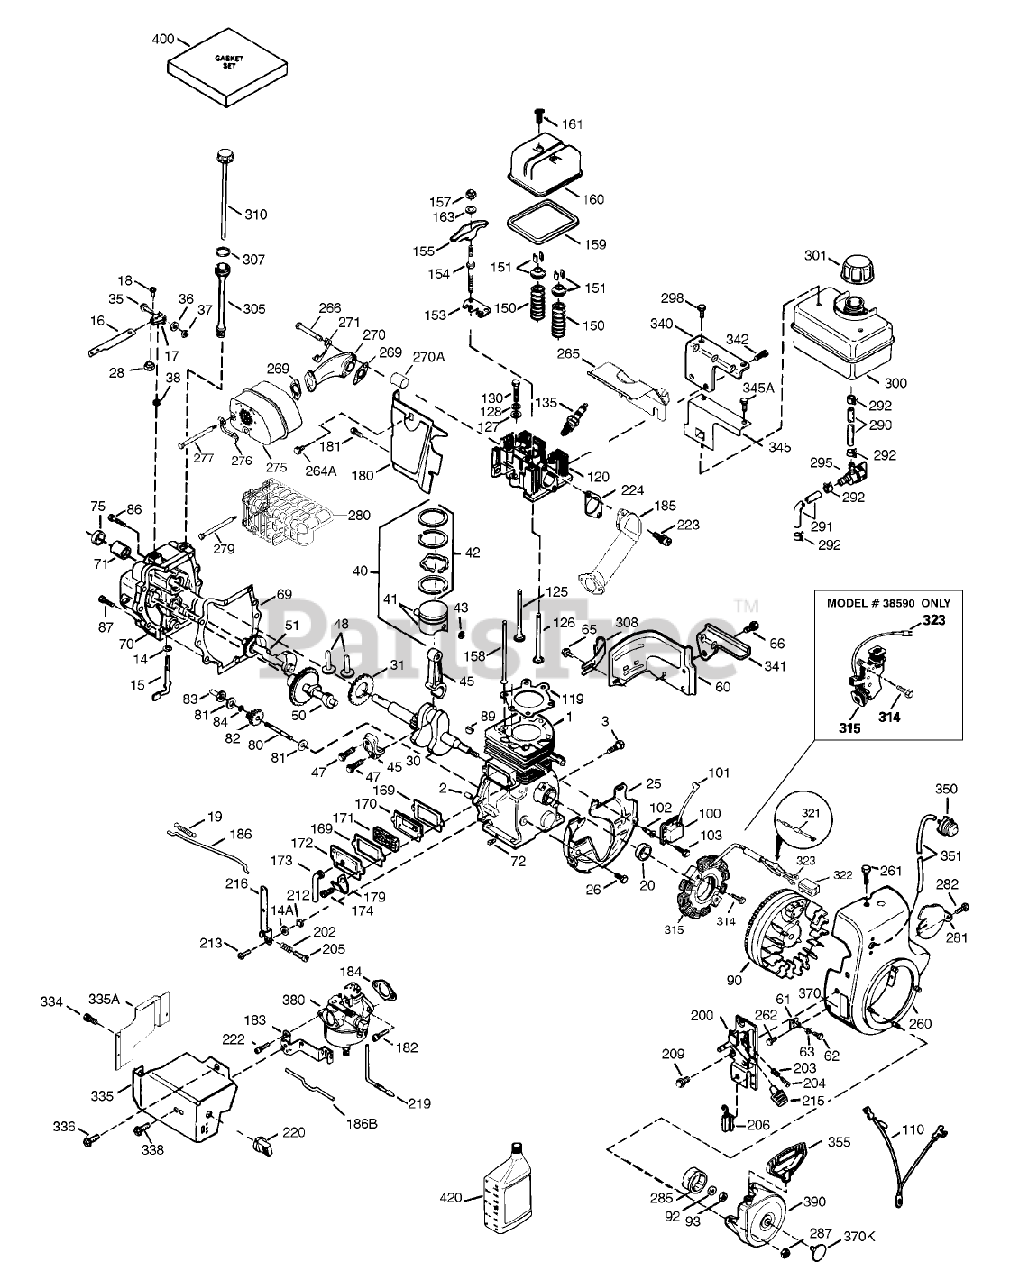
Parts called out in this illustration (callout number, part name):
1	Cylinder (Incl. 2, 20, 72 80)
2	Pin-Dowel
3	Screw (1/4-20x1/2)
14	Washer-Flat
14A	Washer
15	Governor Rod (Incl. Ref.#14 38)
16	Governor Lever
17	Clamp-Lever, Governor
18	Screw (T-15, 8-32x7/16)
19	Throttle Spring
20	Seal-Oil
25	Baffle-Housing, Blower
26	Screw (1/4-20x19/32)
28	Nut-Lock
30	Crankshaft
31	Counterbalance Gear
35	Screw
36	Washer-Lock
37	Nut-Lock
38	Ring-Retaining
40	Piston Pin and Ring ASM (STD)
40	Piston Pin and Ring ASM (.010)
40	Piston Pin and Ring ASM (.020)
41	Piston Pin Ass-y(Std.)(Incl. 43)
41	Piston Pin Ass-y (.010" OS)(Incl. 43)
41	Piston Pin Ass-y.(.020" OS)(Incl. 43)
42	Ring Set (STD)
42	Ring Set (.010)
42	Ring Set (.020)
43	Retaining Ring-Piston Pin
45	Connecting Rod ASM (Incl. Ref. #47)
47	Bolt-Rod, Connecting
48	Lifter-Valve
50	Camshaft
51	Counterbalance Weight
60	Extension-Housing, Blower
61	Bracket
62	Screw (8-32 x 3/8)
63	Grommet
65	Screw (10-24 x 9/16)
66	Screw (1/4-20x19/32)
69	55072/75/86/89 TWO
70	Cylinder Cover (Incl. Ref. #14, 15, 38, 71, 75)
71	2025A77 WIZARD ROTA
72	Plug-Drain, Oil (SQH 1/4-18)
75	Seal-Oil
80	Governor Shaft
81	Washer
82	Gear-Asm Governor
83	Governor Spool
84	Ring-Retaining
86	Screw (1/4-20x1-3/16)
87	Screw (1/4-20x1-11/16)
89	Key-Flywheel
90	Flywheel (W/Ring Gear)
90	Flywheel ASM
92	Washer-Belleville
93	Nut-Flywheel
100	Solid State ASM
101	Cover-Spark Plug
102	Stud-Mounting, Solid State
103	Screw (T-15, 10-24 x 15/16)
110	Ground Wire
119	Cylinder Head Gasket
120	Cylinder Head
125	Valve-Exhaust (STD)
125	Valve-Exhaust (1/32)
126	Valve-Intake (STD)
126	Intake Valve (1/32)
127	Washer-Flat
128	Washer-Belleville
130	Screw (5/16-18 X 2-1/2)
135	Spark Plug-Resistor (R N 4C)
150	Spring-Valve
151	Keeper-Spring, Valve
153	Guide-Rod, Push
154	Stud-Arm, Rocker
155	Arm-Rocker
157	Nut-Jam
158	Rod-Push
159	Gasket-Cover, Rocker Arm
160	Cover-Arm, Rocker
161	Screw
169	Gasket-Cover, Valve
170	Body-Breather
171	Element-Breather
172	Cover-Valve
173	Tube-Breather
174	Screw
179	Retainer Clip
180	Extension-Housing, Blower
181	Screw (10-24 x 9/16)
182	Screw (T-30, 1/4-20 X 27-32)
183	Bracket-Choke
184	Gasket-Carburetor To Intake Pipe
185	Pipe-Intake
186	Governor Link
186B	Spring-Choke
200	Bracket-Control (Incl. Ref. #203, 204 and 206)
202	Compression Spring
203	Spring-Compression
204	Screw (T-10, 5-40x7/16)
205	Screw
206	Terminal
209	Screw (10-32 x 1/2)
212	Bushing
213	Screw
215	Knob-Control
216	Lever-Adjusting
219	Rod-Choke
220	Knob-Control
222	Screw (10-32 x 1/2)
223	Screw (T-30, 5/16-18 X 7/8)
224	Gasket-Pipe
260	Blower Housing
261	Screw (T-30, 1/4-20x15/32)
262	Screw
264A	Screw
265	Cover-Head, Cylinder
266	Screw (5/16-18 X 1-9/32)
269	Gasket-Manifold, Exhaust
270	Idler Pulley
270	Exhaust Manifold
270A	Liner-Port, Exhaust
271	Plate-Locking
275	Muffler
276	Plate-Locking
277	Screw (5/16-18 X 4-1/2)
279	Screw
280	Spring Assist
281	Screw
282	Screw (8-32 x 3/8)
285	Cup-Starter
287	Nut and Lock Washer (1/4-28)
290	Line-Fuel
291	Line-Fuel (8.62)
292	Clamp-Line, Fuel
295	Valve-Shut Off, Fuel
298	Screw (1/4-15x7/8)
300	Tank-Fuel (Includes 292, 301)
301	Cap-Fuel
305	Tube-Fill, Oil
307	O-Ring
308	Clip-Tube, Fill
310	Dipstick
314	Screw (1/4-20 x 3/4)
315	Alternator Coil (3/5)(Incl. 321-323)
315	Coil-Alternator, 18 Watt (Includes 323)
321	Diode
322	Body-Connector
323	Terminal
334	Screw (8-32 X 5/16)
335	Carburetor Cover
335A	Cover-Carburetor
336	Screw (10-32x1/2)
338	Screw (10-32 x 1/2)
340	55073/76/87/90 SNWT
341	Bracket-Fuel Tank
342	Screw (5/16-18 X 7/8)
345	Baffle-Heat
345A	Cover-Carburetor
350	Primer-Asm
351	Line-Primer
355	Handle-Starter, Mitten Grip
370	Decal-Lubrication
370K	Decal-Tecumseh Logo for Top of Recoil Starter
380	Carburetor (Incl. Ref.# 184)
390	Starter-Rewind
400	Gasket Set
420	Oil-Engine (SAE 5W30)
